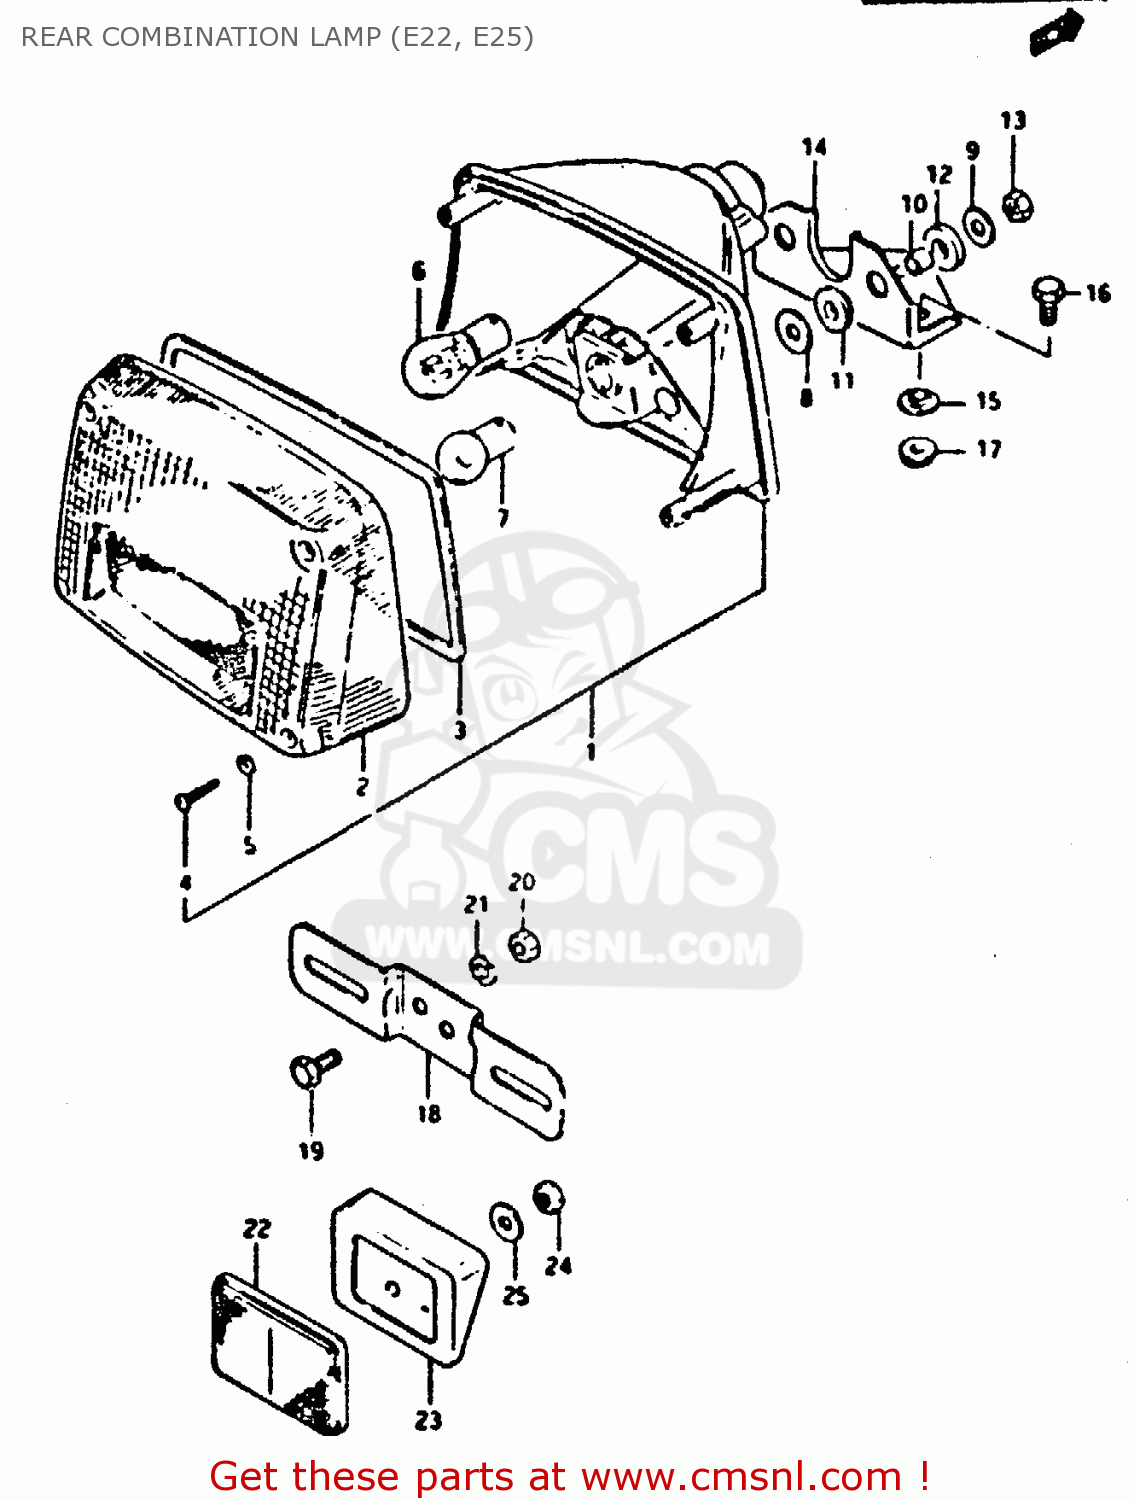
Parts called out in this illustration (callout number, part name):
1	LAMP ASSY, REAR COMBINATION
2	LENS
3	GASKET (NAS)
4	SCREW,REAR COMBINATION LAMP
5	GASKET (NAS)
6	BULB(12V21/5W)
7	BULB
8	WASHER
9	WASHER(6,5X22X1.6)
10	SPACER(6.1X9X7.5)
11	CUSHION
12	CUSHION
13	NUT 6MM
14	BRACKET,RR COMBINATION LAMP
15	WASHER
16	BOLT, UPPER
17	NUT 6MM
18	BRACKET, LICENSE PLATE
19	BOLT,REAR
20	NUT
21	LOCK WASHER
22	REFLEX REFLECTOR,RR
23	SPACER
24	NUT
25	WASHER(5.2X16X1)
